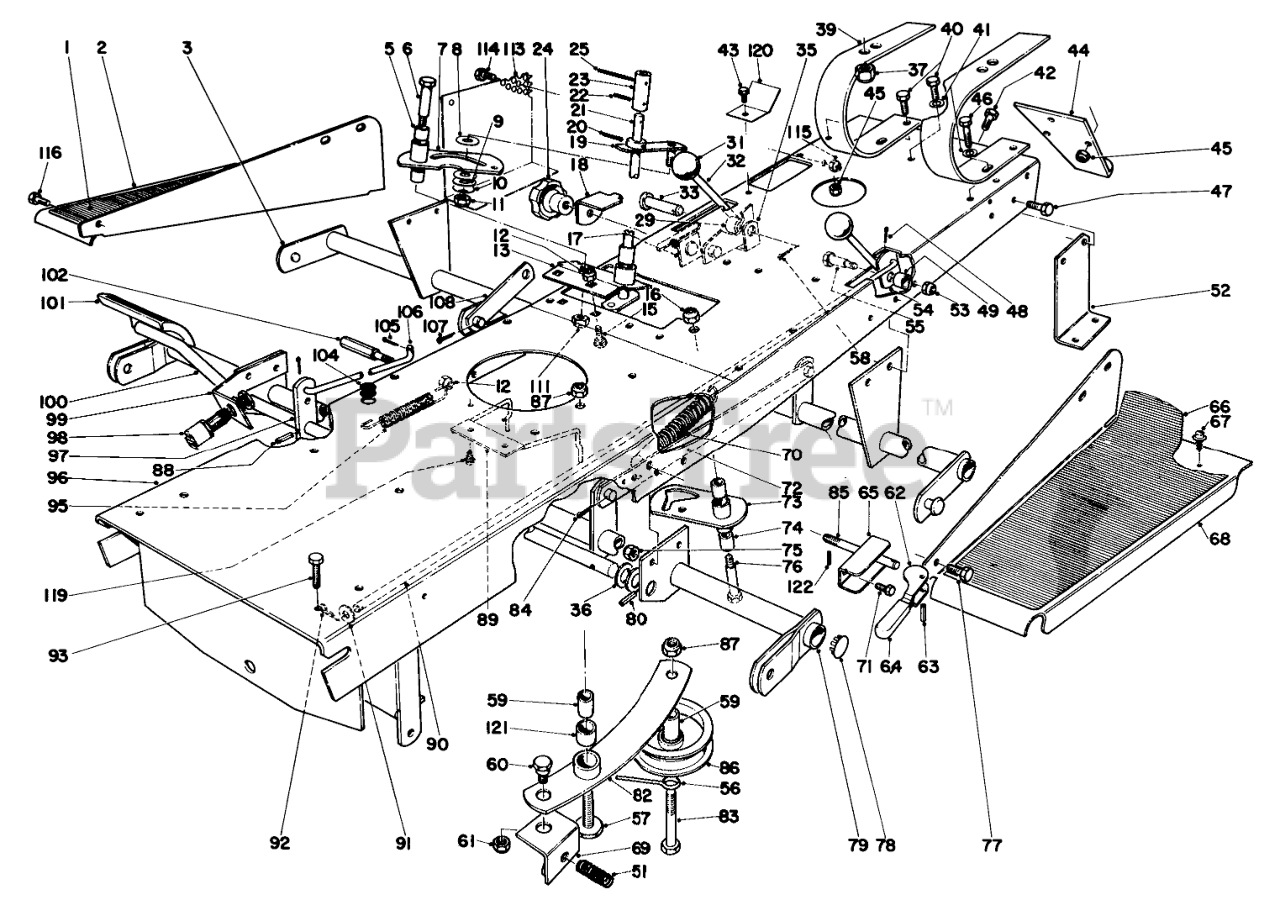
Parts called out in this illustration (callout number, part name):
1	Pad R. H.
2	Footrest R.H.
3	Cross Tube
5	BUSHING
6	Shoulder Bolt
7	Cam Plate (Incl. Ref. #5)
8	Washer
9	WASHER-FLAT
10	Spring Washer
12	Nut
13	Bracket-Control
15	BOLT-CARR
17	Knob Plate
18	Slide
19	Control Crank
20	PIN-SPRING
21	Handle Hydro Control
22	PIN-SPRING
23	Sleeve Handle
25	Roll Pin
29	Spacer
32	Lever
35	Support Height of Cut Lever
36	WASHER-FLAT
39	Seat Spring
40	SCREW-HH
41	WASHER-LOCK
42	SCREW-HH
43	10-24X1/2 OVAL HD SEMS
44	Hitch
46	SCREW-HH
47	SCREW-HH
48	PIN-COTTER
49	Spacer
51	Compression Spring
52	Axle Support L.H.
54	Lever
55	Shoulder Bolt
56	Belt Retainer
57	3/8-16 X 1-1/2 BOLT
58	PIN-COTTER
59	Idler Spacer
60	Pulley
61	NUT-LOCK, CONE
62	Idler Crank
63	PIN-ROLL
64	Handle Grip
65	Retainer Idler
66	Pad Left
67	10-16 X 3/8 THDG SCREW
68	Footrest
69	Swivel Bracket
70	Spring Counterbalance
71	10-24X1/2 OVAL HD SEMS
72	Lift Equalizer
73	Plate Neutralizer (Incl. Ref. #74)
74	Bushing
75	Nut
76	Shoulder Bolt
77	SCREW-HH
78	Plug Button
79	Cross Tube Front
80	PIN-SPRING
82	Bracket Idler
83	SCREW-HH
84	PIN-COTTER
85	Adjustment Rod
86	Flat Idler
87	NUT-LOCK, CONE
88	PIN-ROLL
89	Belt Guide
90	Rod Clutch
91	WASHER-FLAT
92	PIN-COTTER
93	He Ha. Screw
95	Spring
96	Frame Hydrostatic
97	Pedal Crank Neutralizer
98	Switch
99	Bracket Switch
100	Pedal
101	PAD-BRAKE
102	Brake Stop
104	GROMMET
105	PIN-COTTER
106	Link Neutralizer
107	PIN-COTTER
108	Lift Link
113	Fan Guide Side
114	SCREW-HH
115	NUT-LOCK, CONE
116	SCREW-HH
119	10-32 X 1/2 PHILLIPS
120	Shield Fan
121	.503ID X .875LG BSHG
122	PIN-ROLL, SLOTTED
